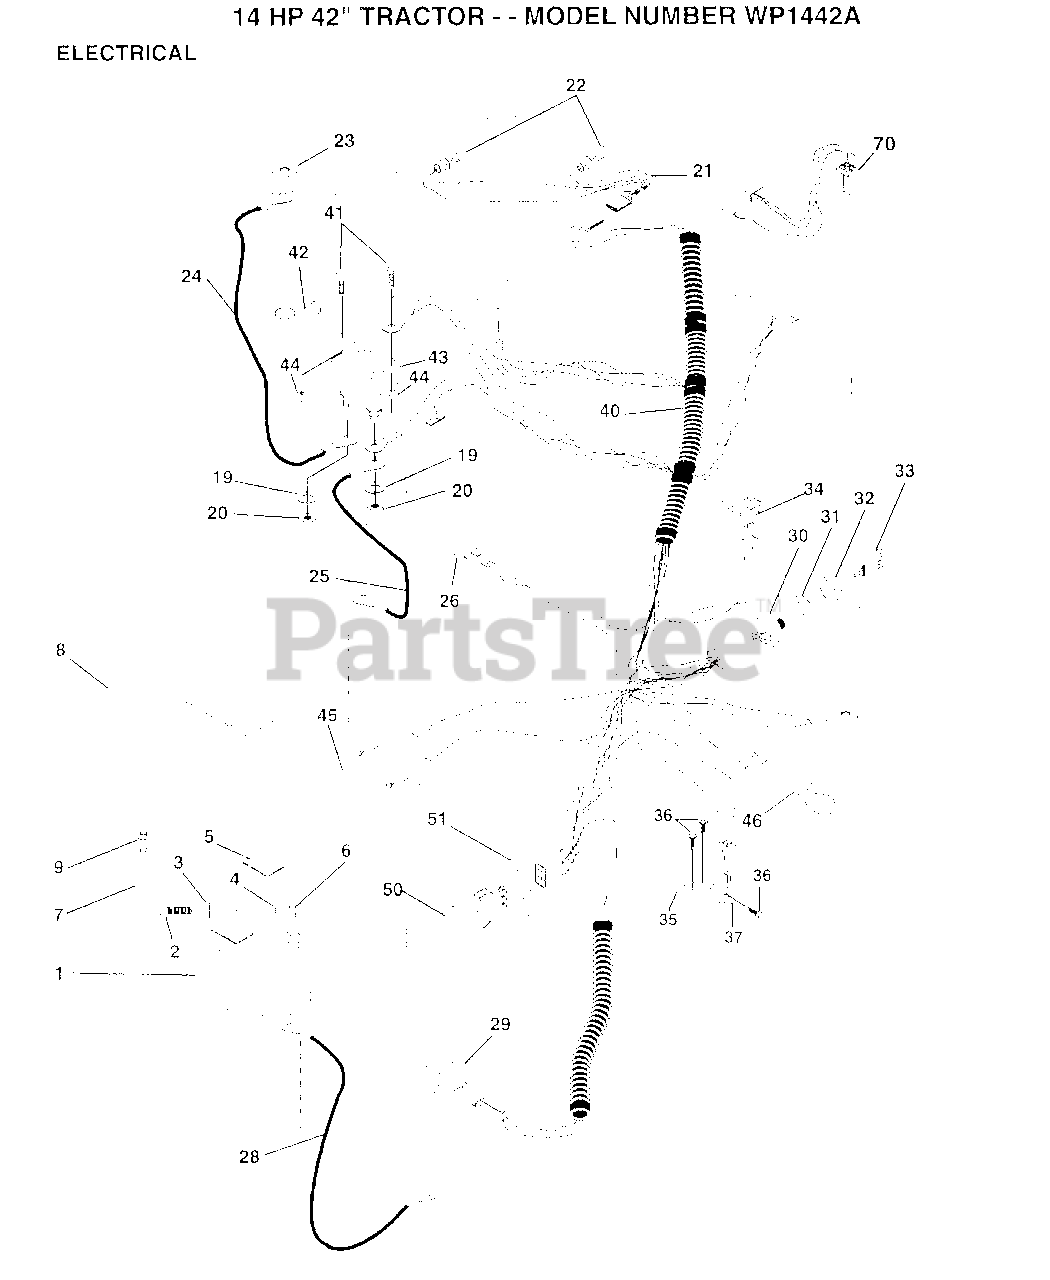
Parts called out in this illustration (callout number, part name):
2	BOLT LT
3	WASHER
4	LOCKWASHER
5	"CAP,BATTERY "
7	TUBE T
9	HOSE CLAMP T
20	NUT
21	"HARNESS,LIGHT SOC"
22	HEADLAMP BULB
23	LOCKWASHER
24	CABLE-BATTERY T
25	CABLE-BATTERY T
26	FUSE HYT
28	CABLE T
29	SWITCH SEAT
32	COVER KEY SWITCH
33	KEY MLD GEN DELTA
34	SWITCH LT
35	BRACKET SWITCH IN
36	SCREW
37	SWITCH-INTER. GT
40	HARNESS IGNITION
41	BOLT HXHD FIN
44	NUT HXKEP 1/4X20
45	ADAPTER AMMETER
51	RING RETAIN PTO
70	HARNESS.ENG.B&S
